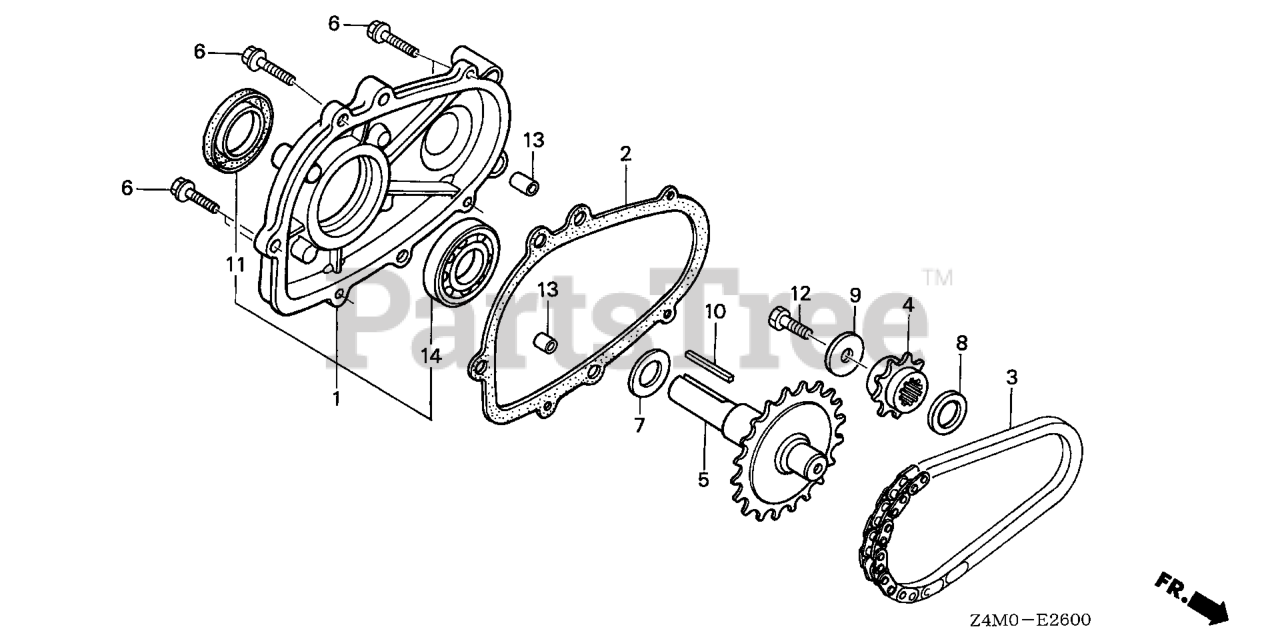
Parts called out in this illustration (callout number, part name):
1	COVER ASSY., CHAIN CASE
2	GASKET, CHAIN CASE COVER
3	CHAIN, P.T.O. DRIVE (DID317FM2-34LE)
4	SPROCKET, DRIVE (13T)
5	SHAFT, P.T.O.
6	BOLT, FLANGE (6X28) (CT200) Use up to Engine SN 1530314.
7	SPRING, THRUST
9	WASHER (8MM)
10	KEY (5X5X33)
11	OIL SEAL (25X41X6)
12	BOLT, HEX. (8X25)
13	PIN A, DOWEL (8X14)
14	BEARING, RADIAL BALL (6205)
